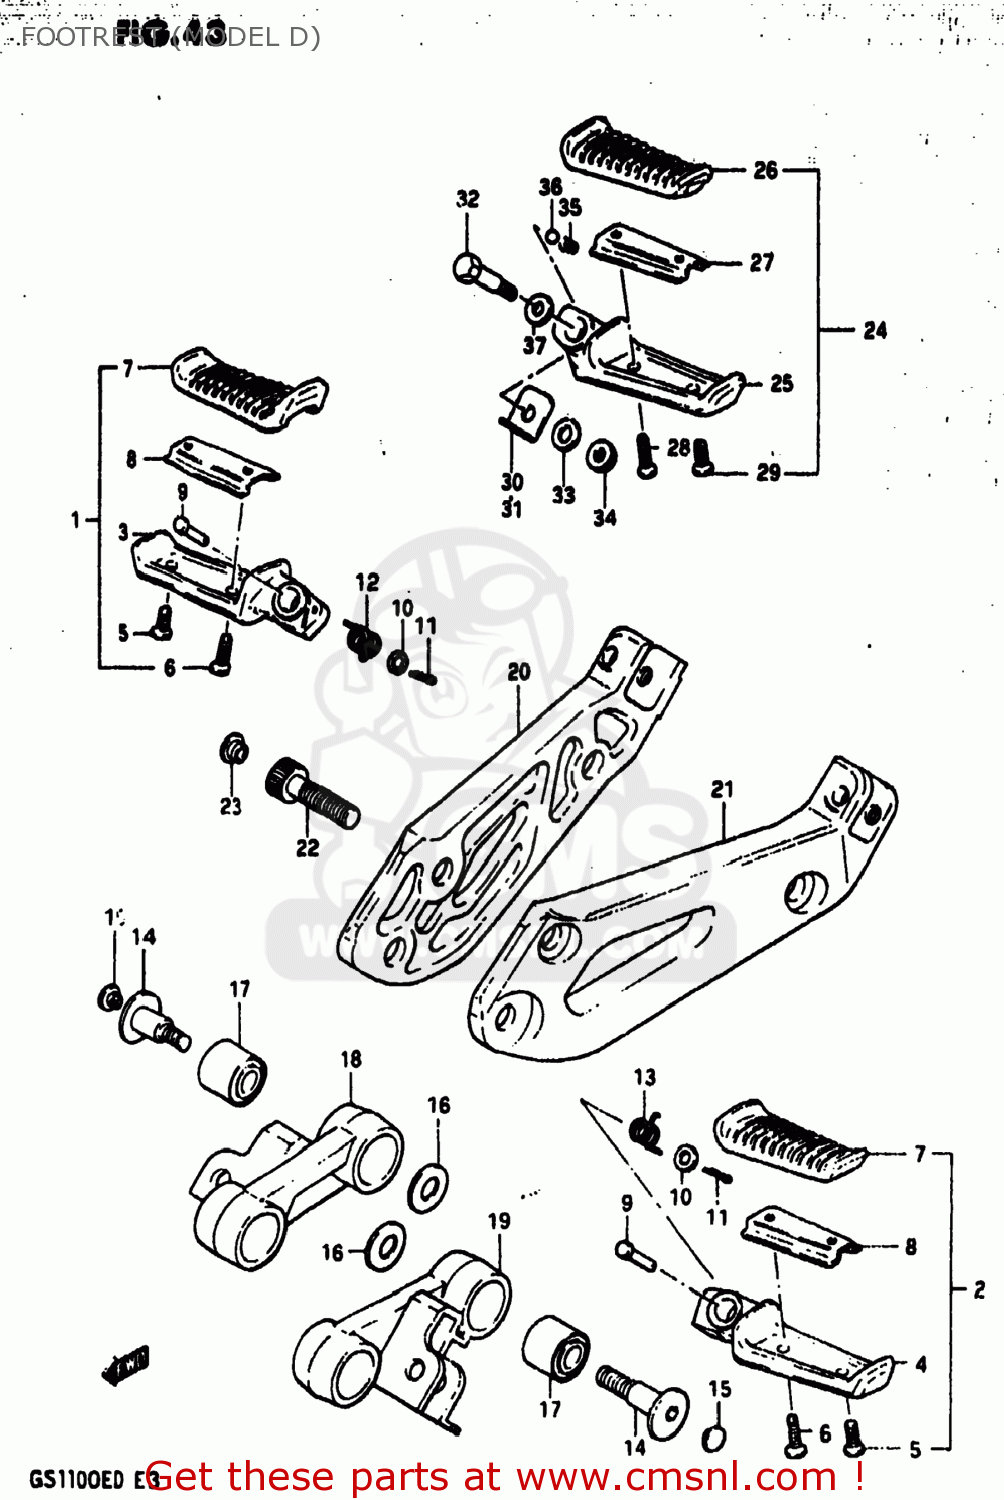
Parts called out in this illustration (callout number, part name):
1	FOOTREST ASSEMBLY,FRONT,RIGHT
2	FOOTREST ASSEMBLY,FRONT,LEFT
3	BAR,FRONT FOOTREST
4	BAR,FRONT FOOTREST,LEFT
5	SCREW
6	SCREW
7	RUBBER,FR FOOTREST
8	PLATE,FRONT FOOTREST RUBBER
9	PIN
10	WASHER
11	PIN 20X20
12	SPRING
13	SPRING
14	BOLT(10X50)
15	CAP
16	WASHER
17	BUSH
18	HOLDER,FRONT FOOTREST,RIGHT
19	HOLDER,FRONT FOOTREST,LEFT
20	BRACKET,MUFFLER,RIGHT
21	BRACKET,MUFFLER,LEFT
22	BOLT
23	CAP
24	FOOTREST ASSY,PILLION,R
25	BAR,PILLION FOOTREST,LEFT
26	RUBBER,PILLION FOOTREST
27	PLATE,RUBBER STOP
28	SCREW 5X12
29	SCREW
30	PLATE,PILLION FOOTREST SPRG,R
31	PLATE,SPRING STOP,LEFT
32	BOLT
33	WASHER
34	NUT
35	SPRING
36	BALL
37	SHIM(8.2X22X0.2)
